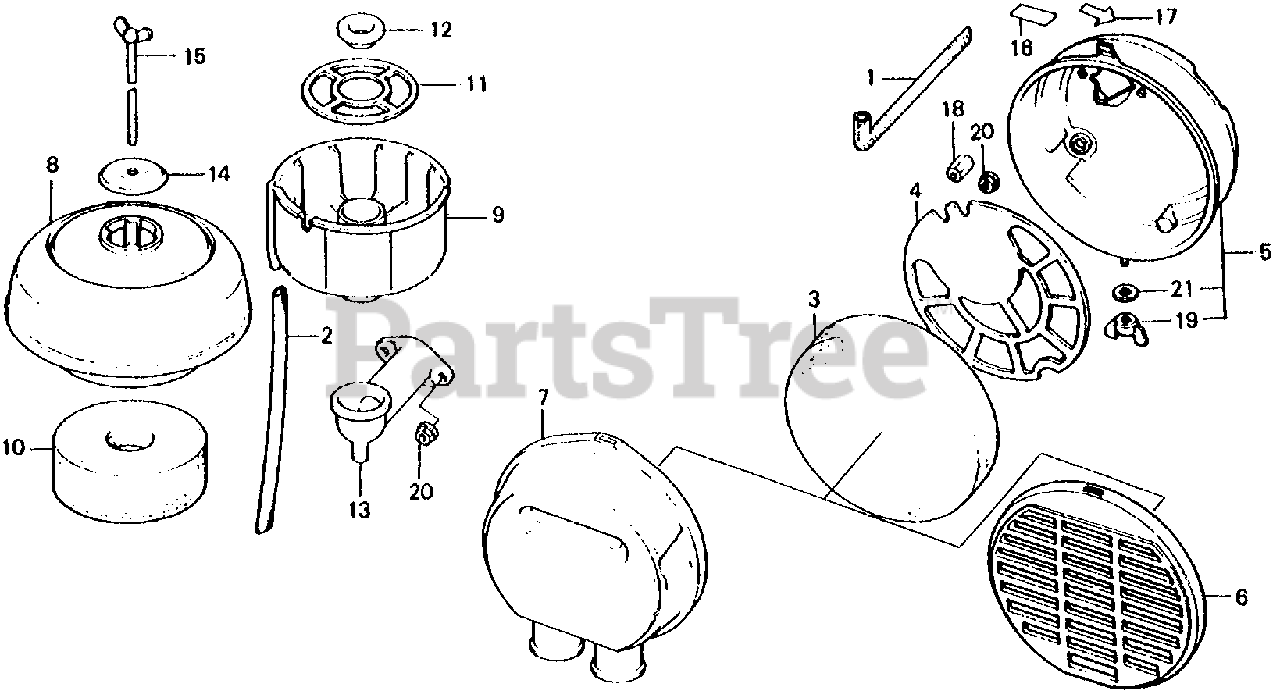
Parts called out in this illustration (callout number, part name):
2	TUBE, BREATHER
7	COVER, AIR CLEANER
8	BODY, CLEANER
9	PAN, AIR CLEANER OIL
10	ELEMENT, AIR CLEANER
11	GRID, AIR CLEANER
12	COLLAR, AIR CLEANER
13	ELBOW, AIR CLEANER
14	CAP, AIR CLEANER
15	BOLT, AIR CLEANER
20	NUT, FLANGE (6MM)
